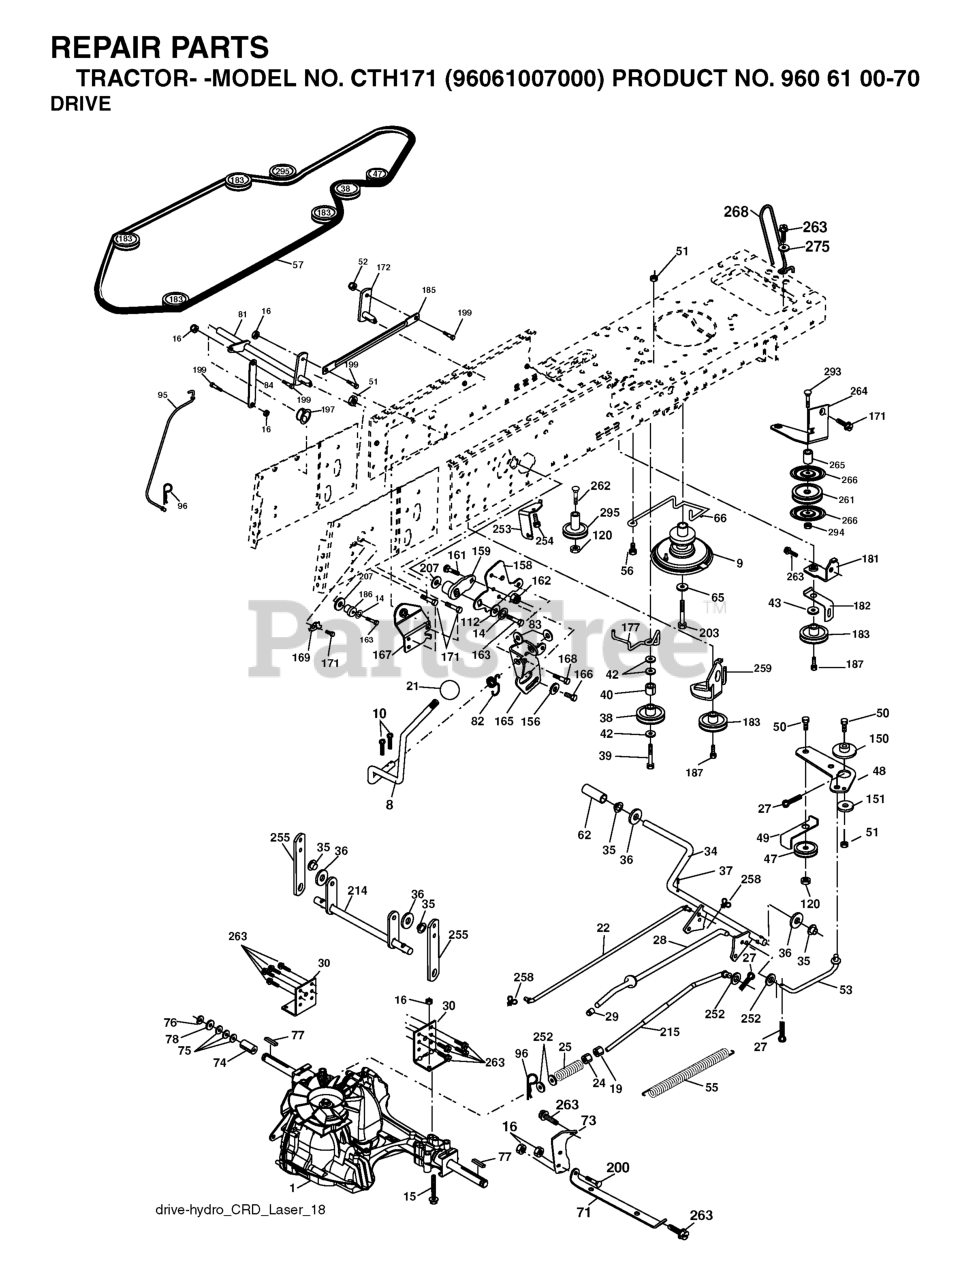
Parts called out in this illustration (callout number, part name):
8	ROD SHIFT FENDER ADJUST LT
9	RP.CLUTCH.NORAM.2006.5
10	PIN COTTER
14	LOCKWASHER
15	BOLT HEX 5/16-18 GR 5
16	NUT.71038.31-18.HEX.NYLOCK
19	NUT
21	KNOB.DUCKHEAD.1/2
22	ROD
24	NUT
25	SPRING BRAKE ROD
27	COTTER PIN
28	ROD, PARKING BRAKE
29	PLUNGER CAP
30	BRKT, TRNSXLE MNT 20"
34	SHAFT, FOOT PEDAL
35	BEARING.NYLON
37	DRIVE PIN
38	PULLEY.FLAT
42	WASHER
47	IDLER PULLEY
48	BELLCRANK, CLUTCH
49	RETAIN BELT
50	BOLT.3/8-16X1.50
52	LOCKNUT
53	LINK.CLUTCH.7.66.2005
55	SPRING, RETURN LT
56	SCREW.3/8-16
57	V-BELT 113"
62	COVER, PEDAL (1 2)
65	LOCKWASHER
66	KEEPER BELT ENGINE
71	STRAP TORQUE RH HYDRO
73	STRAP TORQUE LH HYDRO
74	SPACER AXLE
77	SQUARE KEY
81	ASM.CROSS.SHAFT.REAR.CRD.0510
82	SHIFT SPRING
83	WASHER
84	LINK.PNT.TRANSAXLE.0510.CRD
95	LINK
96	RETAINER M
120	NUT LOCK FLG 3/8-16 UNC
150	BUSHING.BELLCRANK.GRD.DR
151	WASHER 12/32X2X10GA
156	WASHER.SRRTD.5/16
158	BRACKET
159	RB HUB.SHIFT
161	BOLT
162	NUT.CROWNLOCK.1/4
165	RP BRACKET
166	CAPSCREW.HXHD.FLG.5/16-18X.625
167	BRACKET.SUPT.SHIFT.CRD
168	BOLT.SHOULDER.5/16-18X
169	PLATE.FASTENING.CROSS.SHAFT
172	LINK
181	BRACKET
182	BELT GUIDE
183	PULLEY.V-IDLER.GRND.DR
184	SCREW.HXWSH.3/8
185	LINK
186	HUB.TAPERED.ROUND.CRD
187	BOLT.5/16-18X1.25
197	NYLINER SNAP 5/8" ID
199	BOLT SHOULDER 5/16-18 UNC
203	BOLT.HEX.7/16-20 X 5
207	WASHER NYL
214	LEVER
215	ROD
252	WASHER
254	SCREW 3/8-16X1
255	SHAFT
258	CLIP RETAINER
259	BRACKET
261	FLAT IDLER PULLEY
263	SCREW, 3/8-16X3/4
266	PROTECTOR
268	GUARD MUFFLER
275	WASHER
292	SPACER
293	BOLT.RDHD SQNK 3/8-16 X 3-1/2
294	NUT.HEX.3/8-16
295	PULLEY IDLER COMPOSITE
